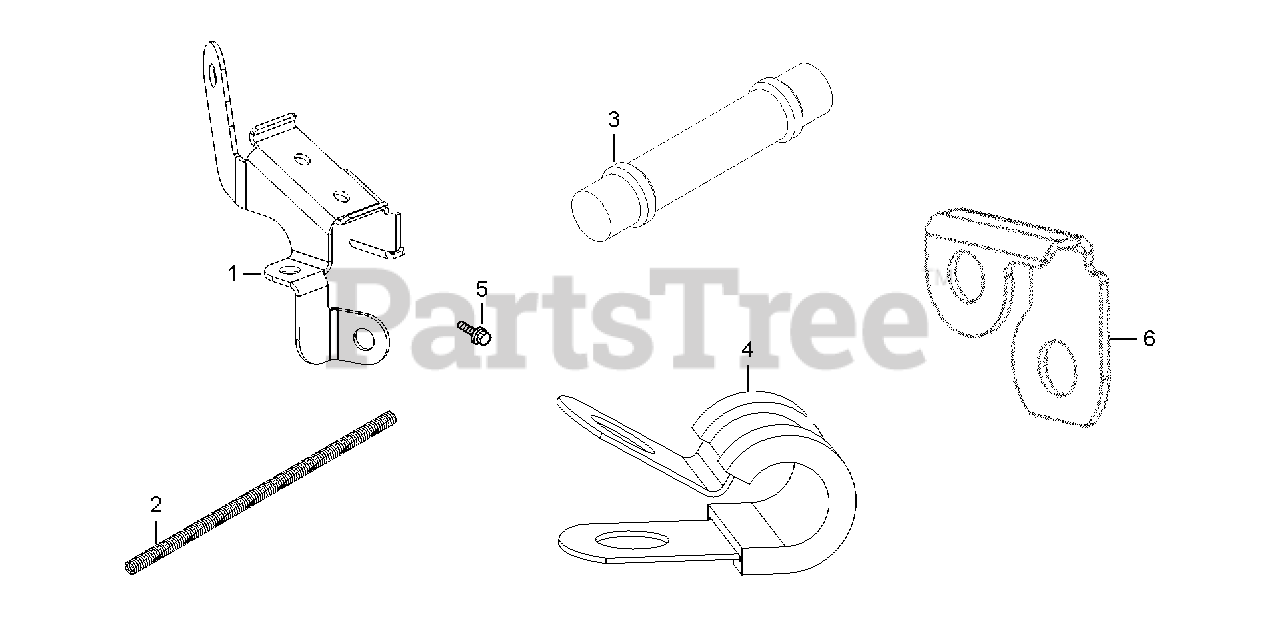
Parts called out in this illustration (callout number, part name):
1	BRACKET, IST RIGGING
2	LOOM, CORRUGATED
3	PLUG, GROMMET
4	CLAMP, CABLE
5	BOLT, FLANGE (6X14)
6	BRACKET, IST CLIP
